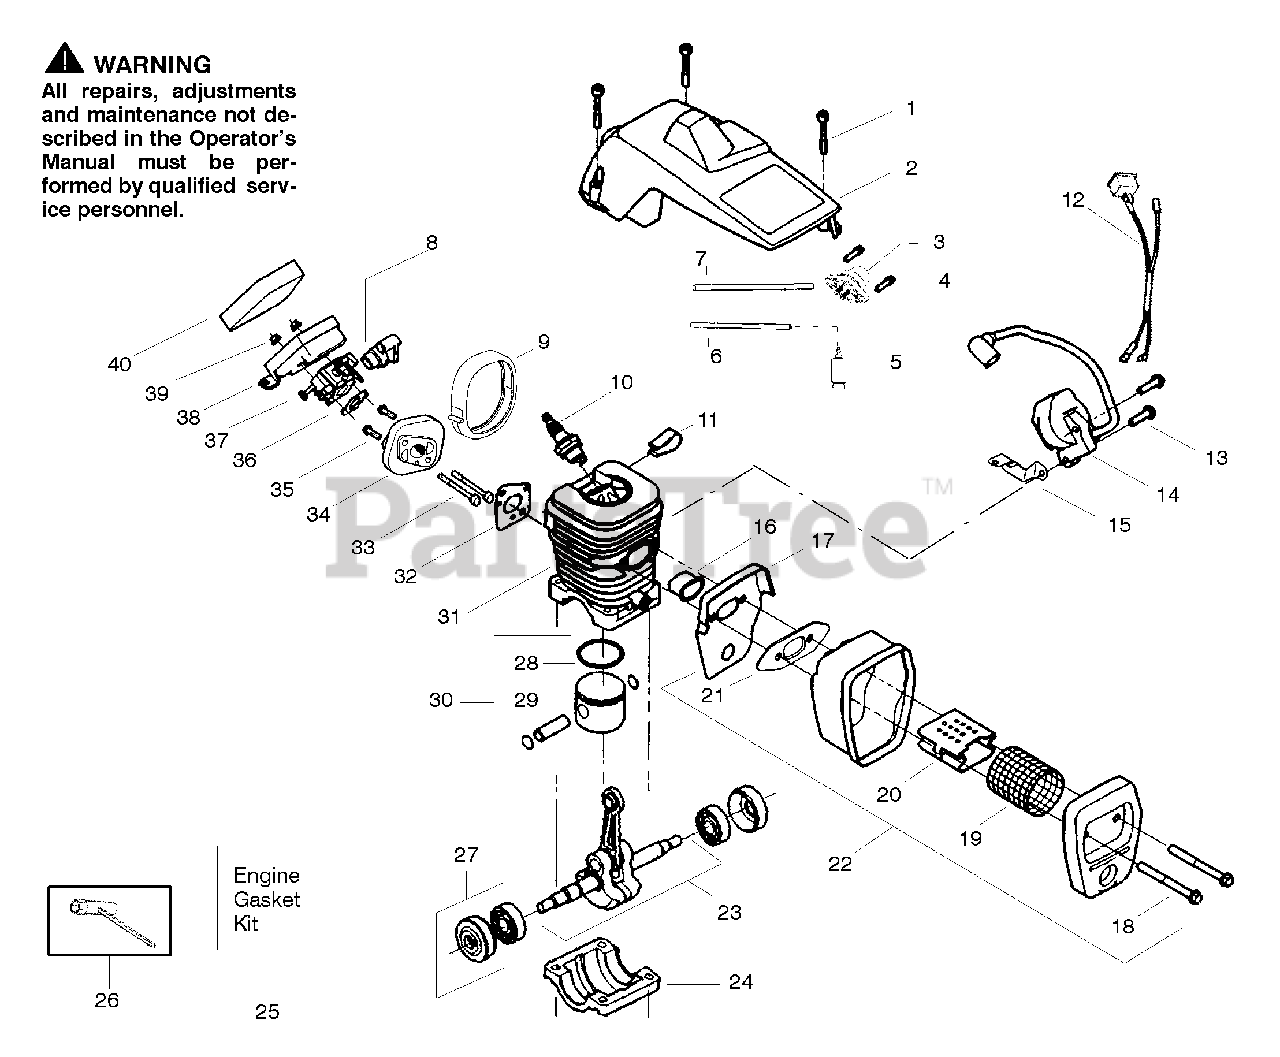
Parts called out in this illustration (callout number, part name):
2	Shield-Cylinder
3	Kit-Purge Bulb
5	Assy-Fuel Pick-up
6	Kit-Line Purge/Carb. (Small Dia)
7	Kit-Line Purge/Tank (large line)
8	Grommet-Carb Adjust.
9	Seal-Carb Adapter
10	Spark Plug (RCJ-7Y)
11	Clip-High Tension Lead
12	Assy-Wire Harness
14	Module-Ignition
15	Strap-Ground
16	Insulator-Heat
17	Back Plate-Muffler
19	Screen-Spark
20	Diffuser-Muffler
21	Gasket-Muffler
22	Assy-Muffler
23	Assy-Crankshaft
24	Cap-Crankcase
25	Kit-Engine Gasket
27	Assy-Seal & Bearing
28	Ring-Piston
29	Retainer - Piston Pin
30	Kit-Piston -
31	Kit-Cylinder
32	Gasket-Carb. Adapter
34	Adapter-Carb.
36	Carb. Gasket
37	Kit-Carburetor (WT-625)
38	Housing-Air Filter
40	Air Filter - Foam
